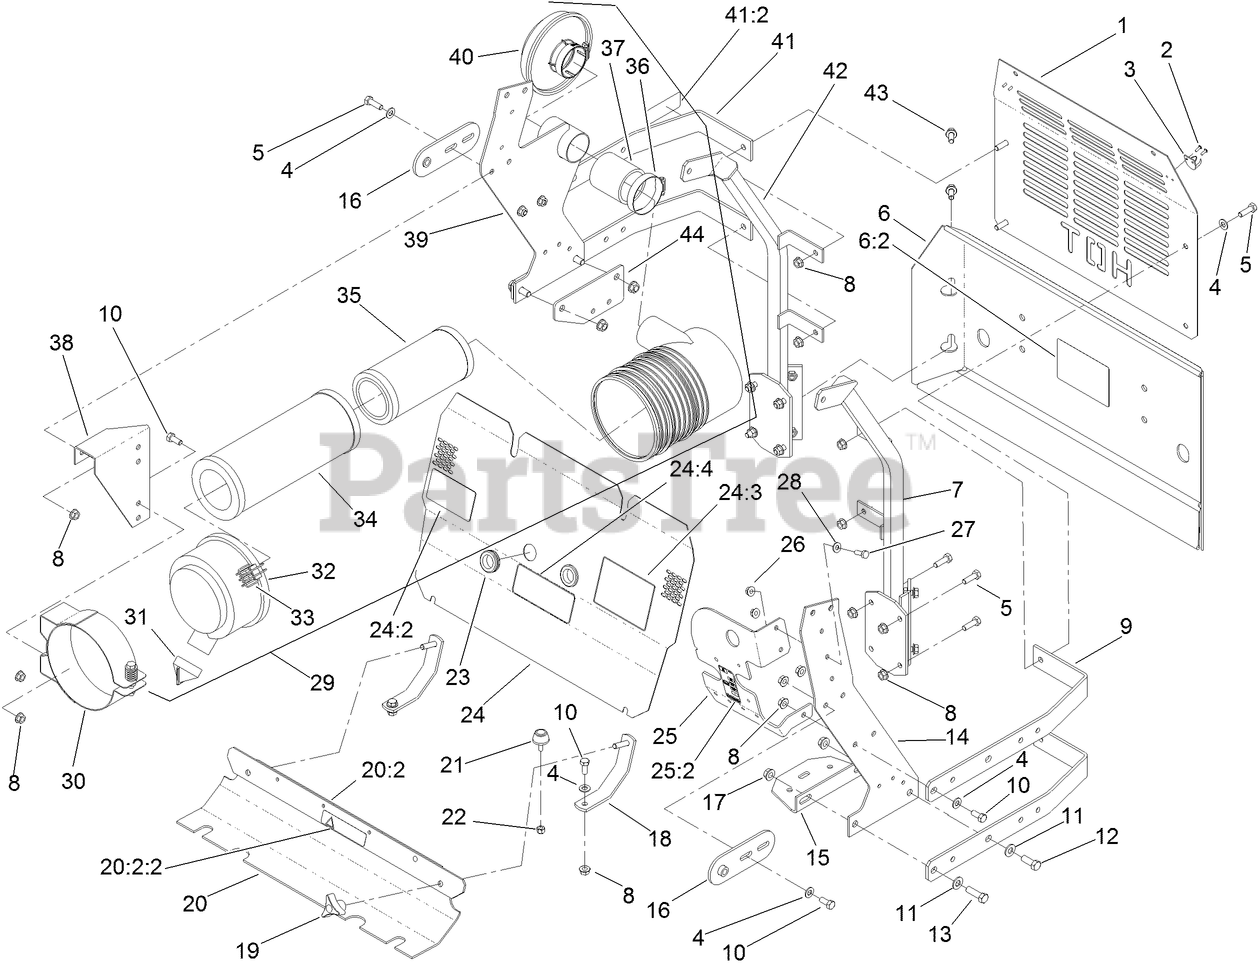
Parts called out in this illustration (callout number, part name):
1	GUARD-MUFFLER
2	RIVET
4	WASHER-PLAIN
5	SCREW-HH
6	REAR BUMPER ASM
6:2	DECAL-BELT ROUTING, DECK DRIVE
7	FRAME-UPPER, LH REAR
8	NUT-HF
9	BAR-MOUNT FRAME, RADIATOR
10	SCREW-HH
11	WASHER-FLAT
12	SCREW-HH
13	SCREW-HH
14	MOUNT-SIDE, LH
15	BRACKET-BOTTLE
16	SHACKLE-HINGE
17	NUT-HHF, WHIZ
18	MOUNT-BELT SHIELD, ENGINE
19	KNOB-3 PRONG
20	ENGINE BELT SHIELD ASM
20:2	Deck ASM
20:2:2	DECAL-COVER, MISSING
21	BUMPER-RUBBER
22	NUT-LOCK, NI
23	GROMMET-RUBBER
24	ENGINE ACCESS PANEL ASM
24:2	DECAL-BELT ROUTING, PUMP
24:3	DECAL-BUZZER, WARNING
24:4	DECAL-DEVICES, ROTATING
25	FUSE/RELAY BRACKET ASM
25:2	DECAL-FUSE
26	NUT-HF
27	SCREW-HH
28	WASHER-FLAT
29	FILTER-AIR
30	BRACKET-FILTER, AIR
31	VALVE-EJECTOR, DUST
32	COVER-FILTER, AIR
33	LATCH-CLEANER, AIR
34	FILTER-AIR
35	FILTER-AIR, SAFETY
36	CLAMP-HOSE
37	HOSE-INTAKE
38	MOUNT-CLEANER, AIR
39	RH RADIATOR AND AC SUPPORT ASM
40	HOOD-CLEANER, 2" AIR INTAKE
41	BAR-RADIATOR
41:2	DECAL-SURFACE, HOT
42	FRAME-UPPER, RH REAR
43	SCREW-HHF
44	PLATE-FUEL FILTER MOUNT
